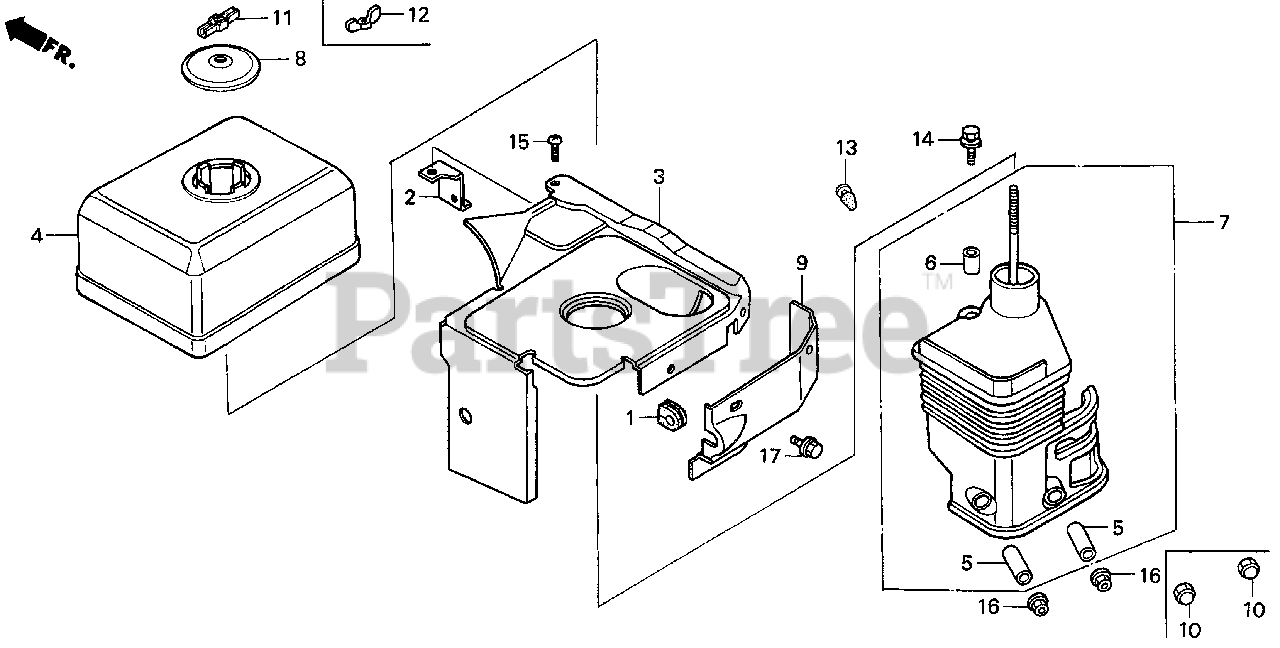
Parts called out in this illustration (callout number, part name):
2	STAY, ENGINE CONTROL COVER
3	COVER, CONTROL
4	COVER, AIR CLEANER (SEMI-DRY)
5	COLLAR, AIR CLEANER
6	COLLAR B, AIR CLEANER
7	ELBOW, AIR CLEANER
8	CAP, AIR CLEANER
12	NUT, TOOL BOX SETTING
13	PLUG, CONE TYPE
14	BOLT, FLANGE (6X20)
16	NUT, FLANGE (6MM)
